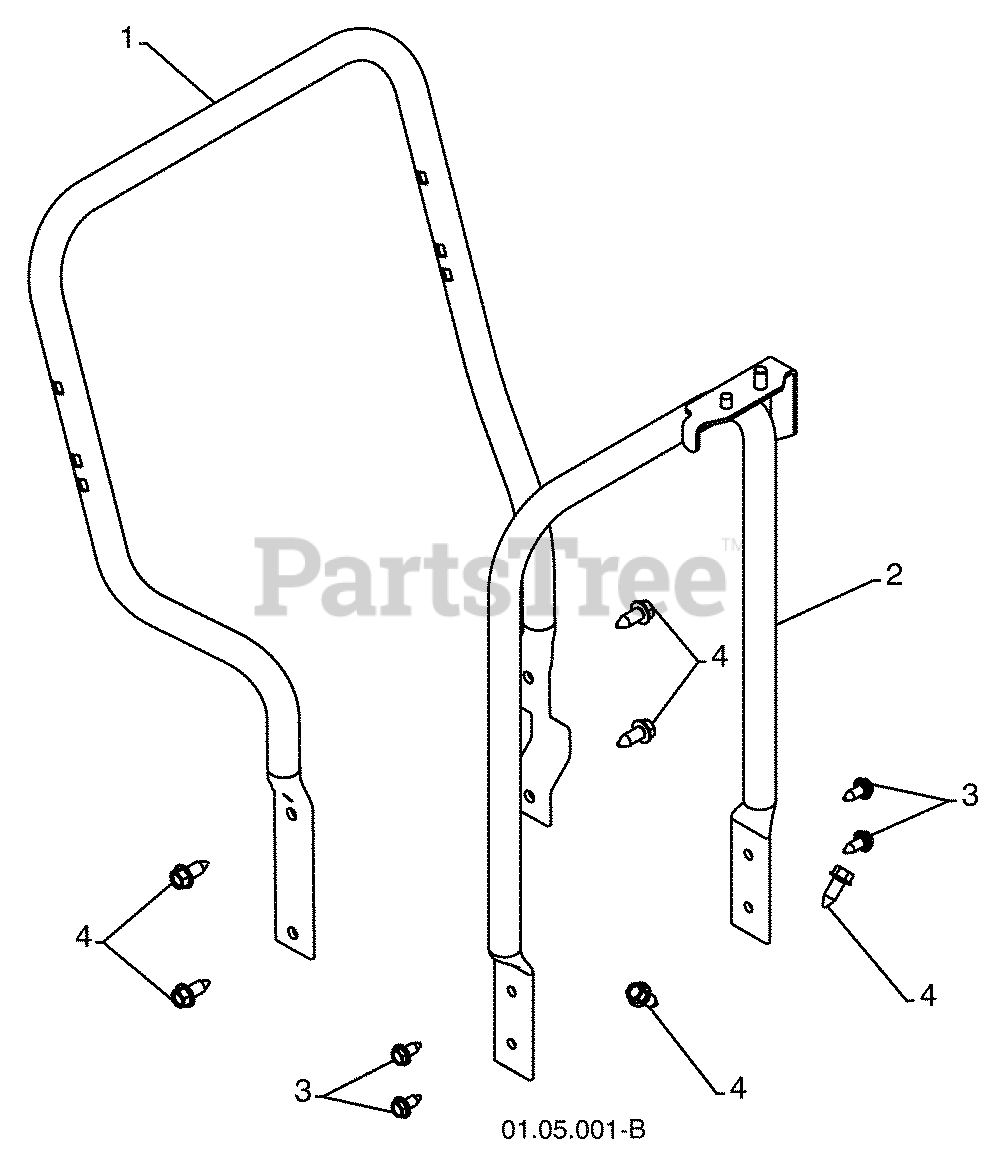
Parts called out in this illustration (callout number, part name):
1	LOWER TUBE
2	PIVOT SUPPORT
3	BOLT 5/16-18 X .750
4	SCREW 3/8-16 X 1.00
